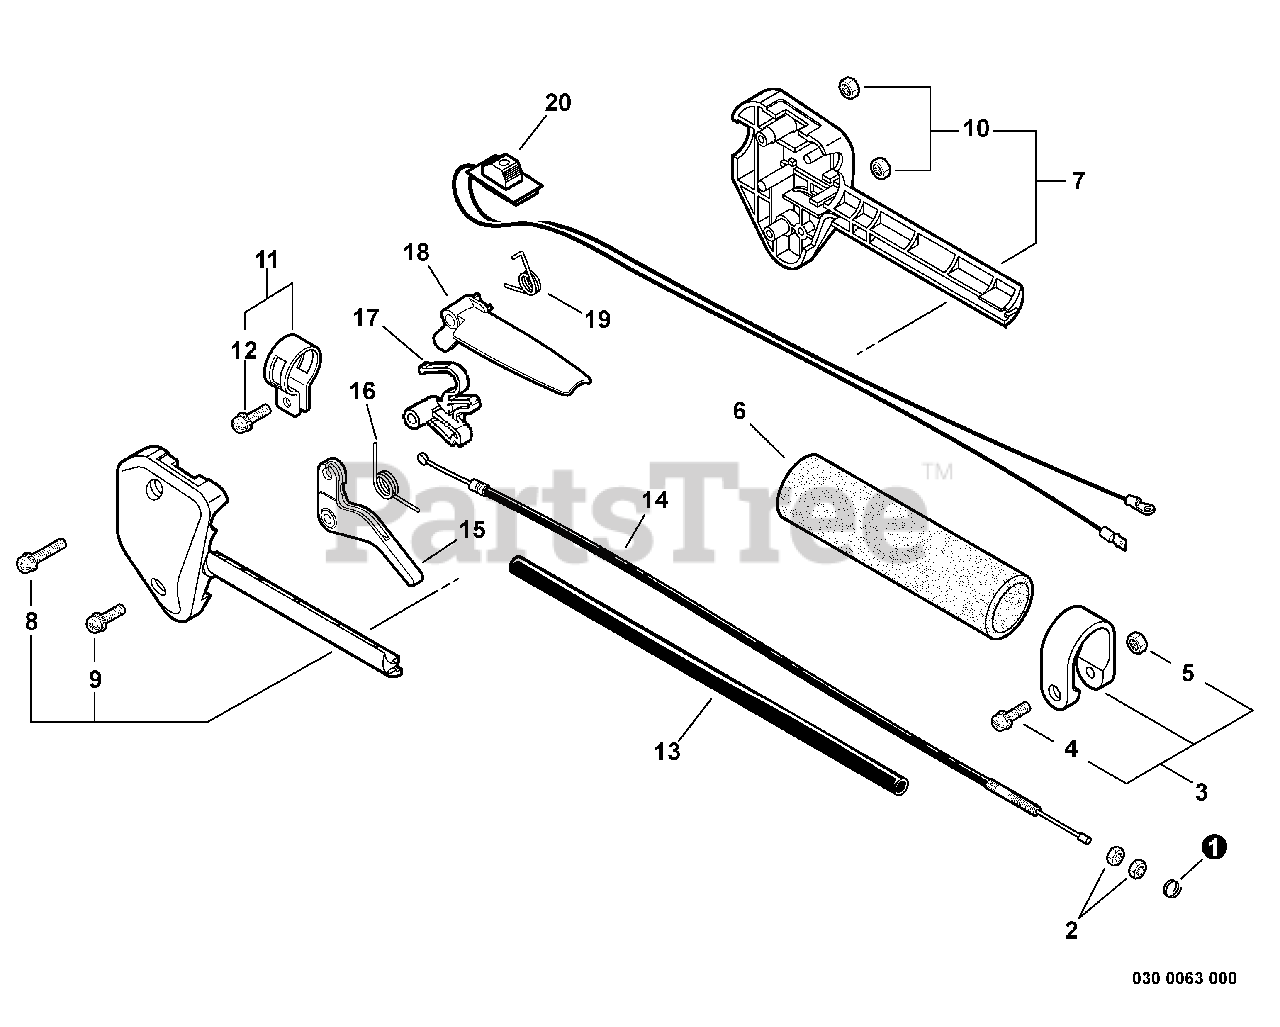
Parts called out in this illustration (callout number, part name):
3	CLAMP KIT
4	SCREW 5×28
5	NUT M5
6	GRIP, HANDLE
7	HANDLE KIT, CONTROL
8	SCREW 5×35
9	SCREW 5×25
10	NUT M5
11	CLAMP KIT
12	SCREW 5×14
13	PIPE, 10×11×180
14	CABLE, THROTTLE 320×77.5
15	TRIGGER, THROTTLE
16	SPRING, TORSION
17	LOCKOUT, THROTTLE
18	LEVER, THROTTLE LOCKOUT
19	SPRING, TORSION
20	SWITCH, ON-OFF
